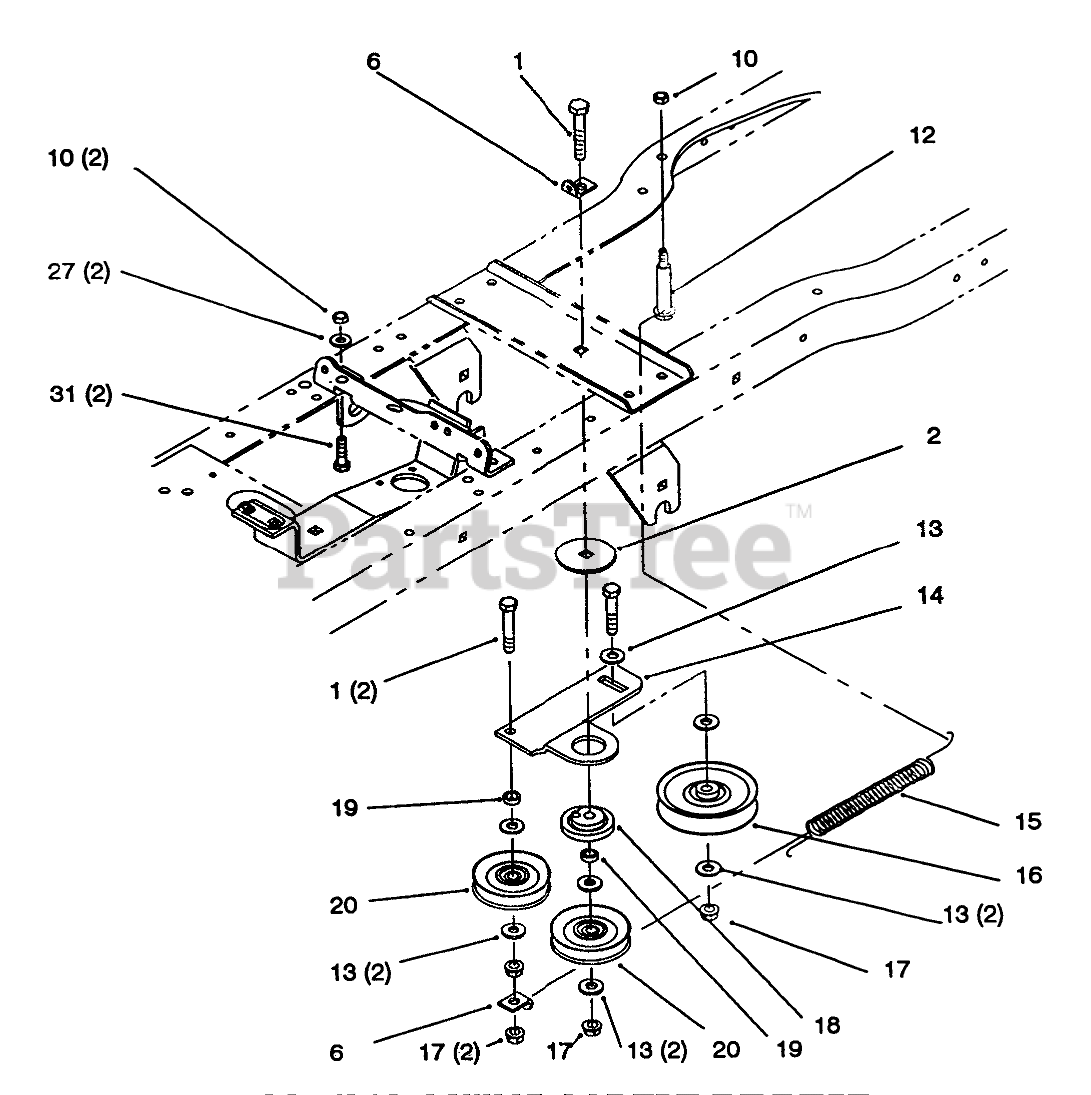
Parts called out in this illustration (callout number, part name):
1	Screw (Only On: 72043, 72103, 72063, 72083)
2	Washer-Bearing (Only On: 72043, 72103, 72063, 72083)
6	Clip-Spring (Only On: 72043, 72103, 72063, 72083)
10	Nut-Hex Lock (Only On: 72103, 72063, 72083, 72043)
12	Bolt-Shoulder (Only On: 72043, 72103, 72063, 72083)
13	Washer-Flat (Only On: 72043, 72103, 72063, 72083)
14	Arm-Idler (Only On: 72043, 72103, 72063, 72083)
15	Spring-Extension (Only On: 72043, 72103, 72063, 72083)
16	Pulley-Flat Idler (Only On: 72043, 72103, 72063, 72083)
17	Nut-Hex Lock (Only On: 72103, 72063, 72083, 72043)
18	Bushing (Only On: 72043, 72103, 72063, 72083)
19	Spacer (Only On: 72043, 72103, 72063, 72083)
20	Pulley-Idler (Only On: 72043, 72103, 72063, 72083)
27	Washer-Flat (Only On: 72103, 72063, 72083, 72043)
31	Screw-HH (Only On: 72043, 72103, 72063, 72083)
